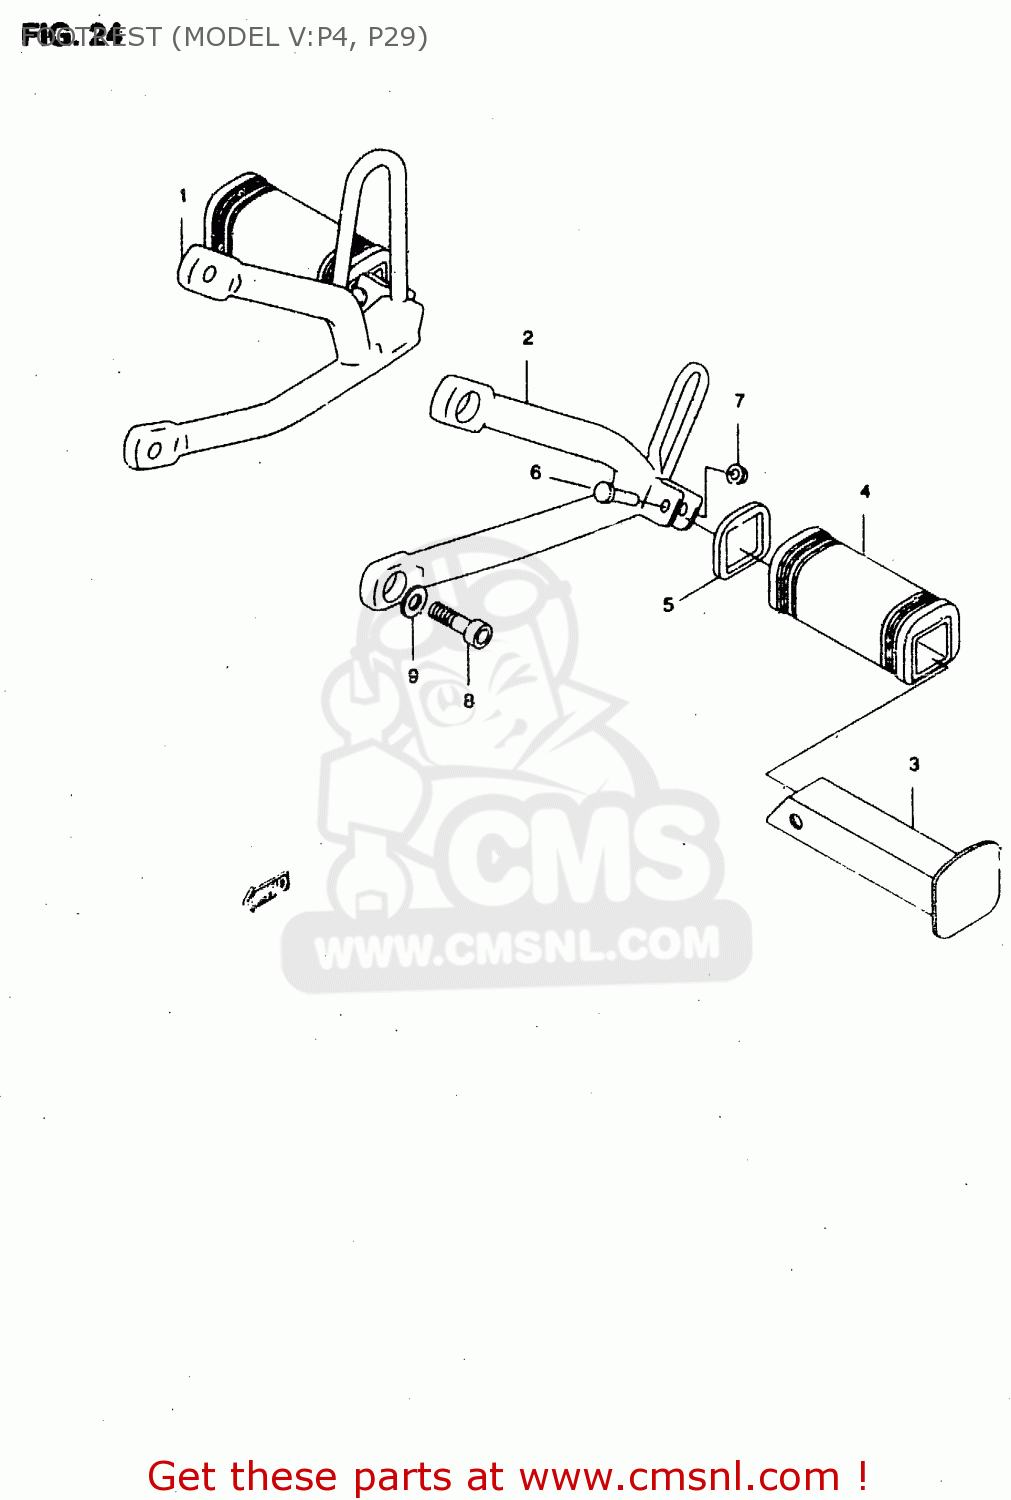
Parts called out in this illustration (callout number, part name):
1	FOOTREST, PILLON RH
2	FOOTREST, PILLON RH
3	BAR,RR FOOTRES
4	RUBBER,PILLION FOOTREST
5	WASHER
6	BOLT(6X35.2)
7	NUT
8	BOLT
9	LOCK WASHER
